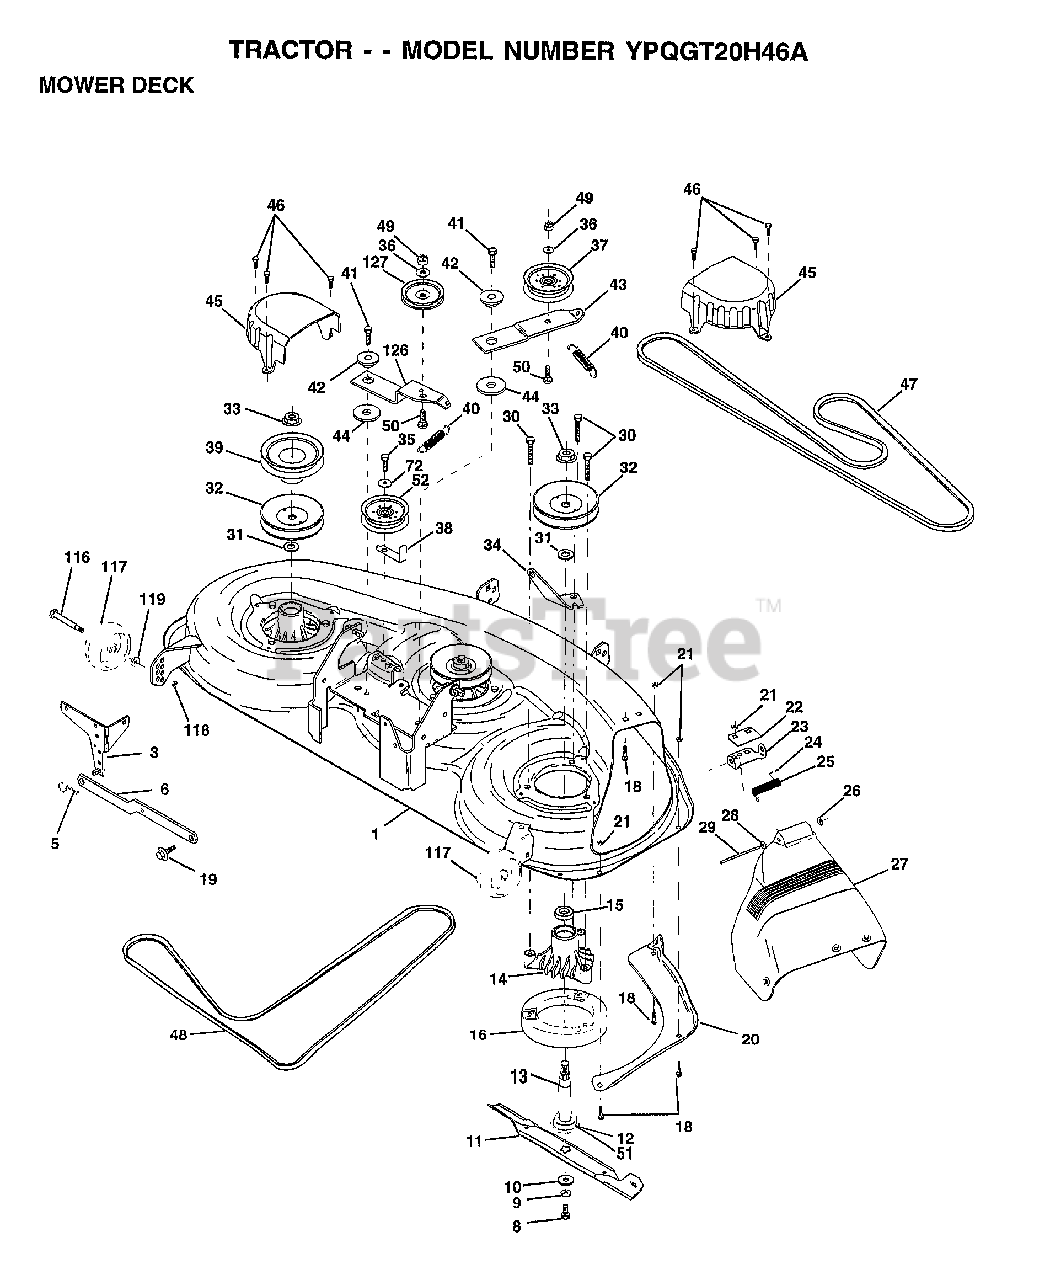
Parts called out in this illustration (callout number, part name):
1	"DECK.ASM.MOWER46"""
3	BRKT.ASM.SW.44/50
8	BLADE BOLT
10	WASHER.HARD.BLADE
11	"BLADE MULCH 46"""
12	BEARING.BALL
13	SHAFT.ASM.W/BRNG
14	HOUSING.MAND.44.V
15	BEARING
16	STRIPPER RND MWR
18	BOLT
19	BOLT SHD 5/16-18
20	BAFFFLE.VORTEX.46
22	STIFFENER BRKT
23	DEFLECTOR BRKT
24	CAP-SLEEVE LT
26	NUT PUSH M
27	SHIELD DEFLECTOR
28	WASHER
29	HINGE ROD
30	"SCREW-THD ROLL,WA"
31	WASHER
32	PULLEY.MAND.36/46
34	ANCHOR.SPRING.46
35	SCREW LT
36	WASHER
37	FLAT IDLER PULLEY
38	"KEEPER BELT,IDLER"
39	PULLEY.DRV.DCK.46
40	"SPRING.SEC.44""VEN"
41	SCREW
42	SPACER.RETAINER.MOWER
43	ARM.IDLER.DECK.46
44	HARDENED WASHER
45	COVER.MANDREL.46
46	SCREW.1/4-20X5/8
47	BELT-V.SEC.46.KEL
48	BELT.MWR.PRM.85.4
50	BOLT.3/8-16X1.50
51	WASHER.FELT.
52	"PULLEY IDLER,FLAT"
72	WASHER HYT
116	BOLT.SHOULDER
117	WHEEL GAGE DONUT
118	LOCKNUT
119	WASHER
126	ARM.IDLER.PRIM.46
127	PULLEY.IDLER.4.25
